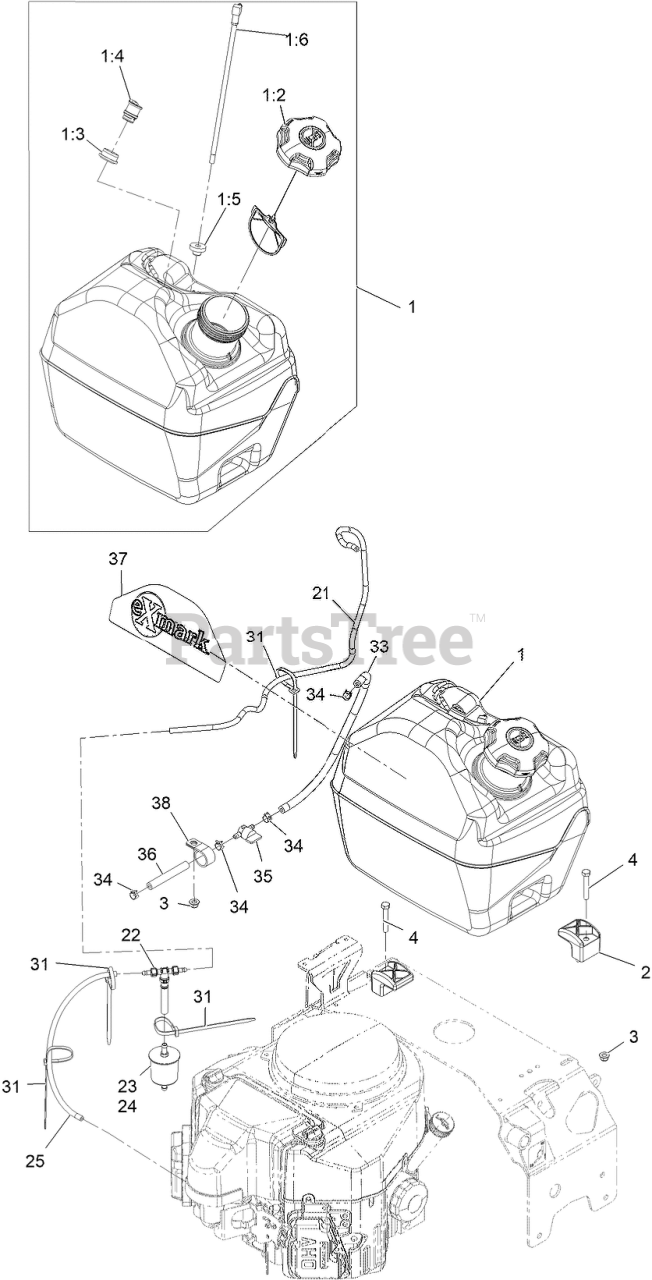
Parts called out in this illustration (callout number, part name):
1	Fuel Tank ASM, 5 Gal
1:2	CAP-FUEL, RATCHETING
1:3	GROMMET
1:4	VALVE-VENT, FUEL
1:5	BUSHING
1:6	FITTING, FUEL W/LINE AND SCREEN
3	NUT-HF, NI
4	SCREW-HH
21	HOSE, EMISSIONS
22	TEE AND CHECK
23	FILTER-FUEL
24	DECAL-FILTER, EMISSIONS
25	HOSE-FUEL
31	TIE-CABLE
33	HOSE-FUEL
34	CLAMP-HOSE
35	VALVE-FUEL
36	HOSE-FUEL
37	Artwork-Exmark Logo Fuel Tank
38	CLIP-LOOM
